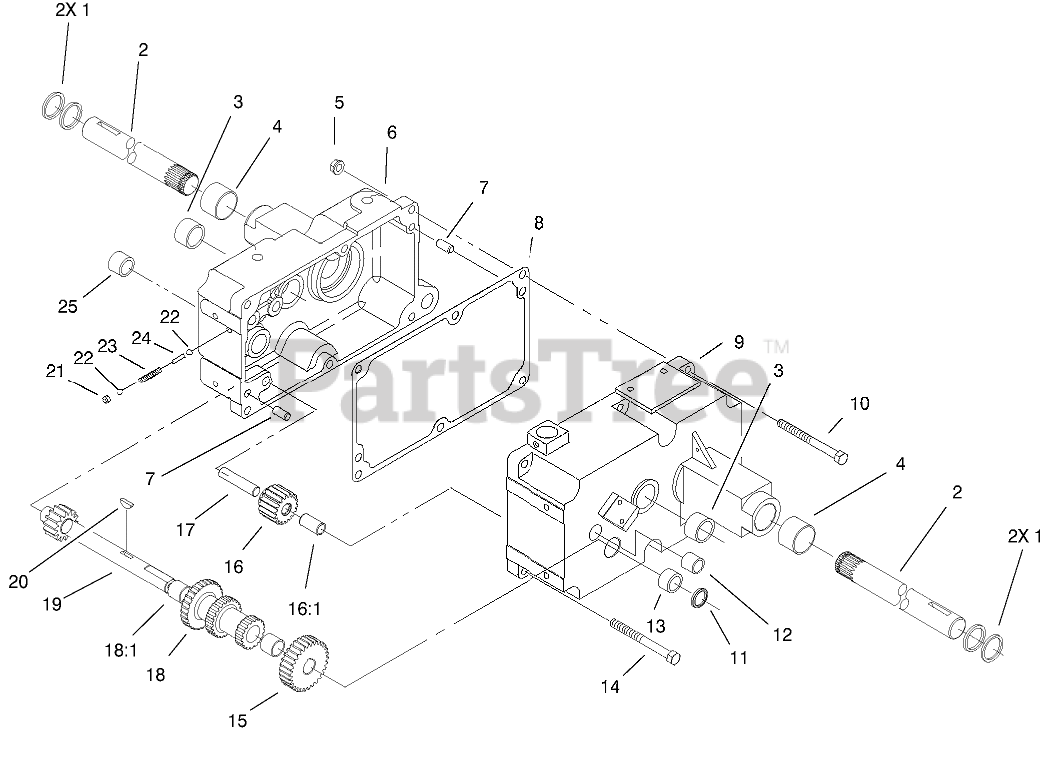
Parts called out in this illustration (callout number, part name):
1	SEAL-OIL
2	AXLE-REAR
3	BEARING-NEEDLE
4	BEARING
5	NUT-LOCK, NI
6	CASE-RH TRANS
7	PIN-DOWEL
8	GASKET-TRANSMISSION
9	CASE-TRANS LH
10	SCREW-HH
11	SEAL-OIL
12	BEARING-NEEDLE
13	BEARING-NEEDLE
14	SCREW-HH
15	GEAR-CLUSTER SHAFT
16	GEAR/BUSHING ASM-REVERSE IDLER
16:1	BUSHING
17	PIN-DIFFERENTIAL
18	GEAR-CLUSTER
18:1	BUSHING-BRONZE
19	SHAFT-CLUSTER
20	KEY-WOODRUFF
21	CUP-PLUG
22	BALL-DETENT
23	SPRING-SHIFT STOP
24	PIN-SHIFT
25	BEARING-NEEDLE
